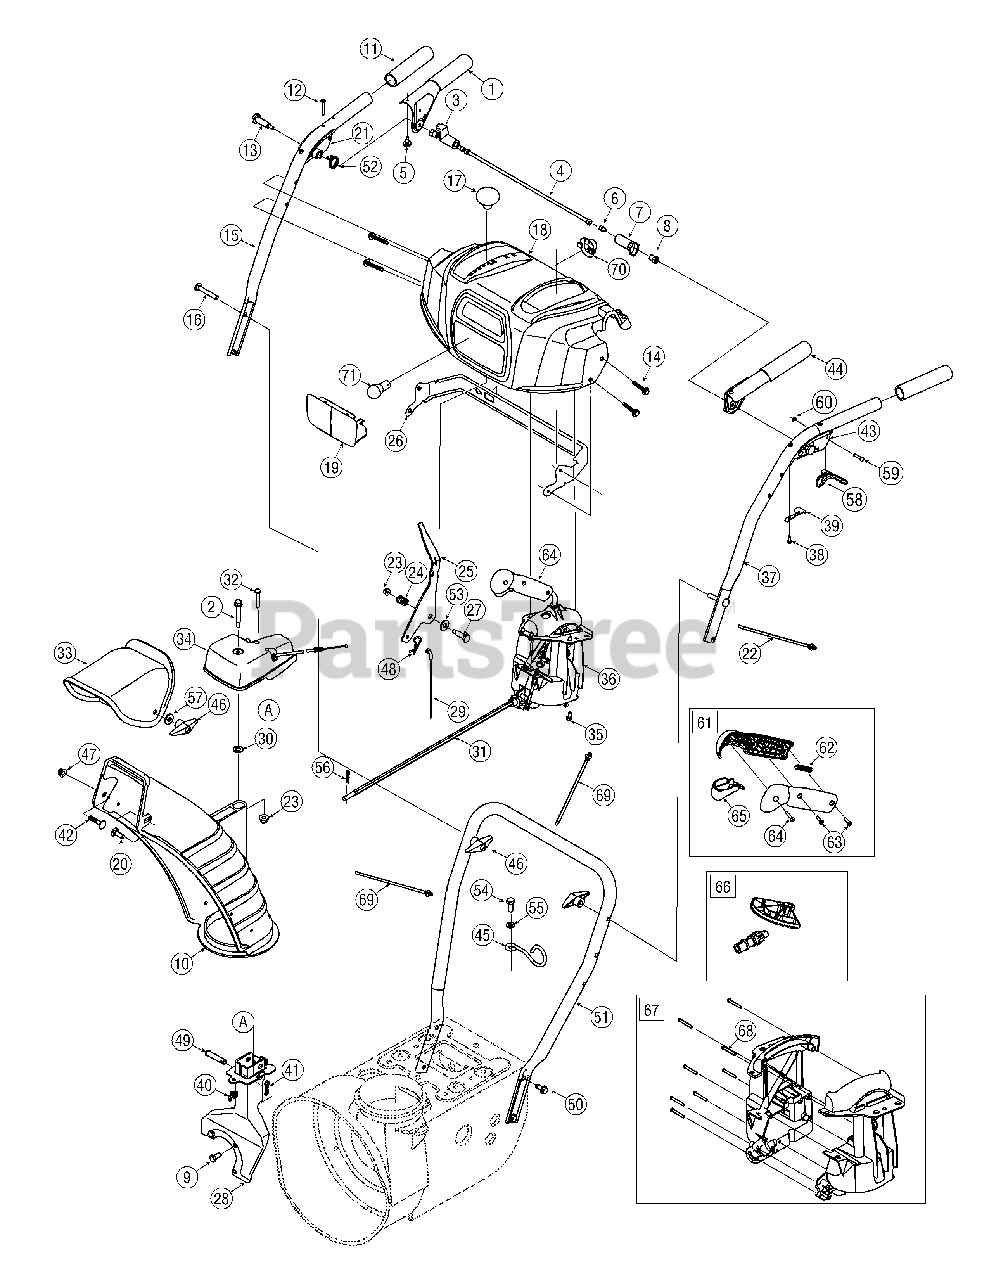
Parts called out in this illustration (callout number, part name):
1	Handle Engagement Assembly RH
2	Flange Shoulder Screw
3	Lock Plate
4	Pivot Rod
5	Rubber Bumper
6	Screw, 1/4-20 x .500
7	Clutch Lock Cam
8	Shoulder Nut, 1/4-20
9	Hex Screw, 5/16-24 x .750
10	Lower Chute
11	Handle Grip
12	Screw, #10-24 x 0.375
13	Shoulder Screw, 1/4-20
14	Screw, 1/4-20 x 1.625
15	Upper Handle RH
16	Carriage Screw, 5/16-18 x 2.25
17	Shift Knob
18	Handle Panel
20	Carriage Bolt, 5/16-18 x 1.0
21	Handle Clutch Lock RH Assembly
22	Cable Tie
23	Flange Lock Nut, 1/4-20
24	Compression Spring
25	Shift Lever
26	Panel Bracket
27	Shoulder Screw
28	Chute Support Bracket
29	Speed Selector Cable
30	Flat Washer, .25 x .630 x .0515
31	Chute Rod
32	Hex Screw, 1/4-20 x 3.00
33	Upper Chute
34	Gearbox Assembly
35	Hi-Lo Screw, 1/4-15 x 0.5
36	2-Way Chute Control Assembly
37	Upper Handle LH
38	Screw, #8-16 x 0.50
39	Clutch Lock Spring
40	Wing Nut, 1/4-20
41	Bow Tie Cotter Pin
42	Carriage Bolt, 5/16-18 x .750
43	Handle Clutch Lock LH Assembly
44	Handle Engagement Assembly LH
45	Cable Control Wire
46	Wing Knob
47	Flange Lock Nut, 5/16-18
48	Click Pin
49	Clevis Pin
50	Screw, 5/16-18 x 0.75
51	Lower Handle
52	Torsion Spring
53	Flat Washer
54	Screw, M8-1.25
55	Flat Washer, .330 x .630 x .0635
56	Cotter Pin
57	Flat Washer, .349 x .879 x .063
58	Steering Control
59	Pin, 3/16
60	E-Ring
61	Handle Assembly
62	Handle Plunger
63	Screw, Mach., #8-32 x .750
64	Screw, #8 x 1.00
65	Handle Lever
66	Gear Set Assembly
67	Handle Housing Assembly
68	Screw, #8-18 x 1.250
69	Cable Tie
70	Light Socket
71	Light
